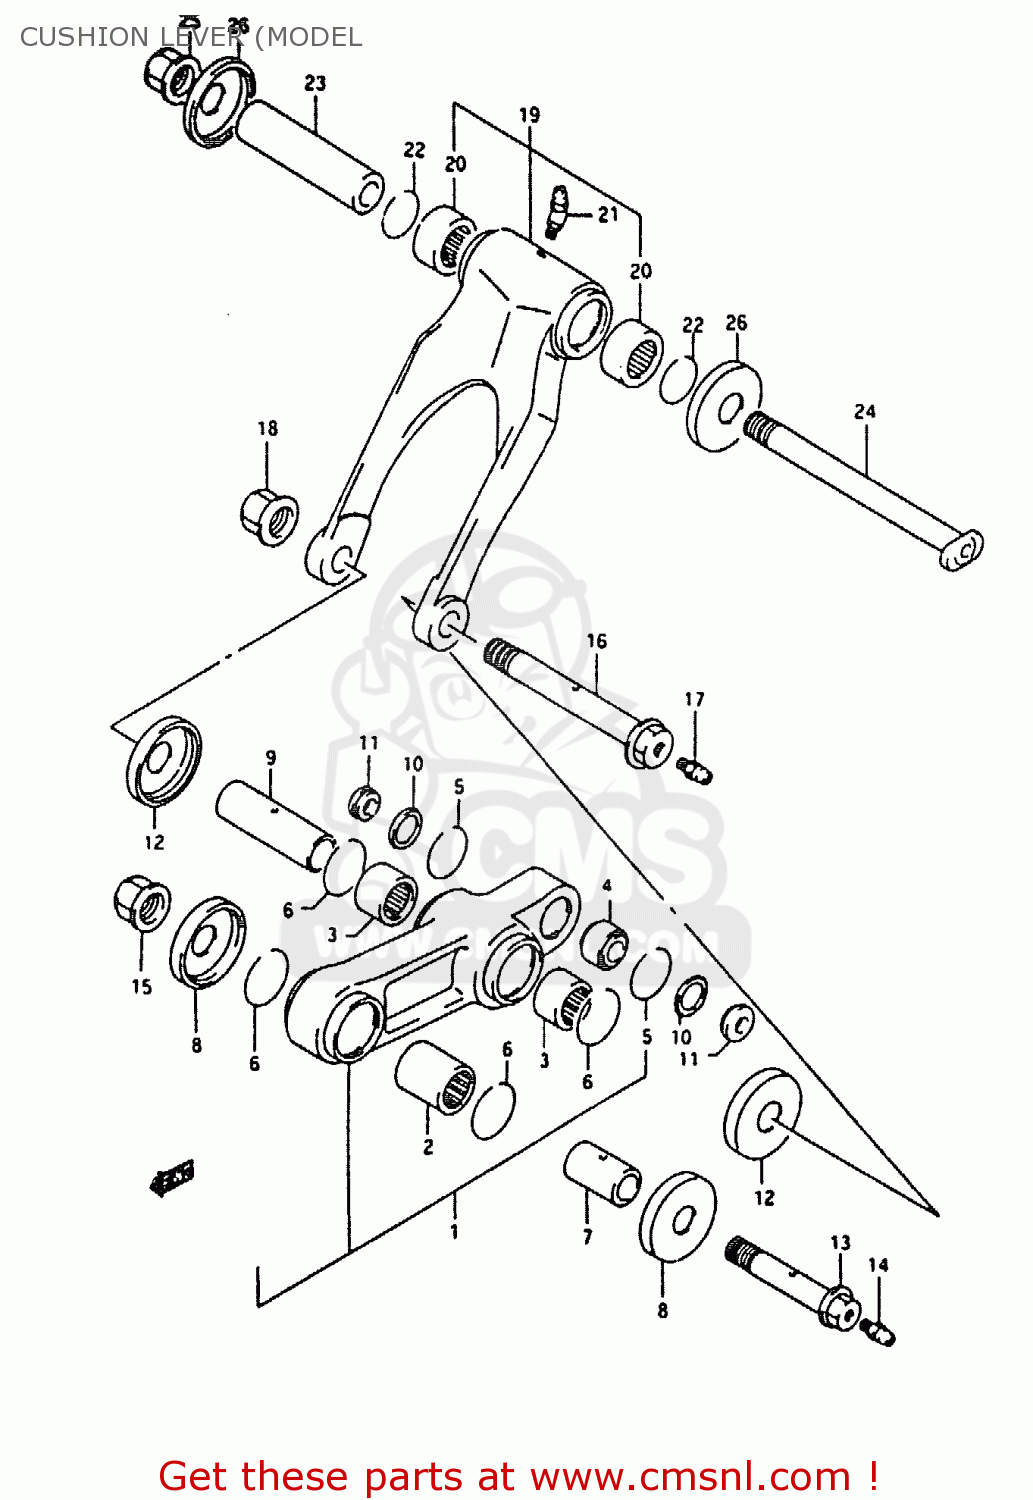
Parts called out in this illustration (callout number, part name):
1	LEVER SET,REAR CUSHION
2	BEARING(20X27X25)
3	BEARING(21X27X20)
4	BEARING,RR CUSHION LEVER
5	RING
6	CIRCLIP
7	SPACER,RR CUSHION LEVER FR
8	SEAL,REAR CUSHION LEVER
9	SPACER,RR CUSHION LEVER CTR
10	SEAL,RR CUSHION LEVER RR DUST
11	SPACER,RR CUSHION LEVER RR
12	SEAL,REAR CUSHION LEVER
13	BOLT,REAR CUSHION LEVER
14	GREASE NIPPLE
15	NUT 12MM
16	BOLT, CENTER
17	GREASE NIPPLE
18	NUT
19	LEVER SET,REAR CUSHION
20	BEARING(21X27X20)
21	NIPPLE, GREASE
22	CIRCLIP
23	SPACER,RR CUSHION ROD
24	BOLT,RR CUSHION ROD
25	NUT
26	SEAL,REAR CUSHION LEVER
